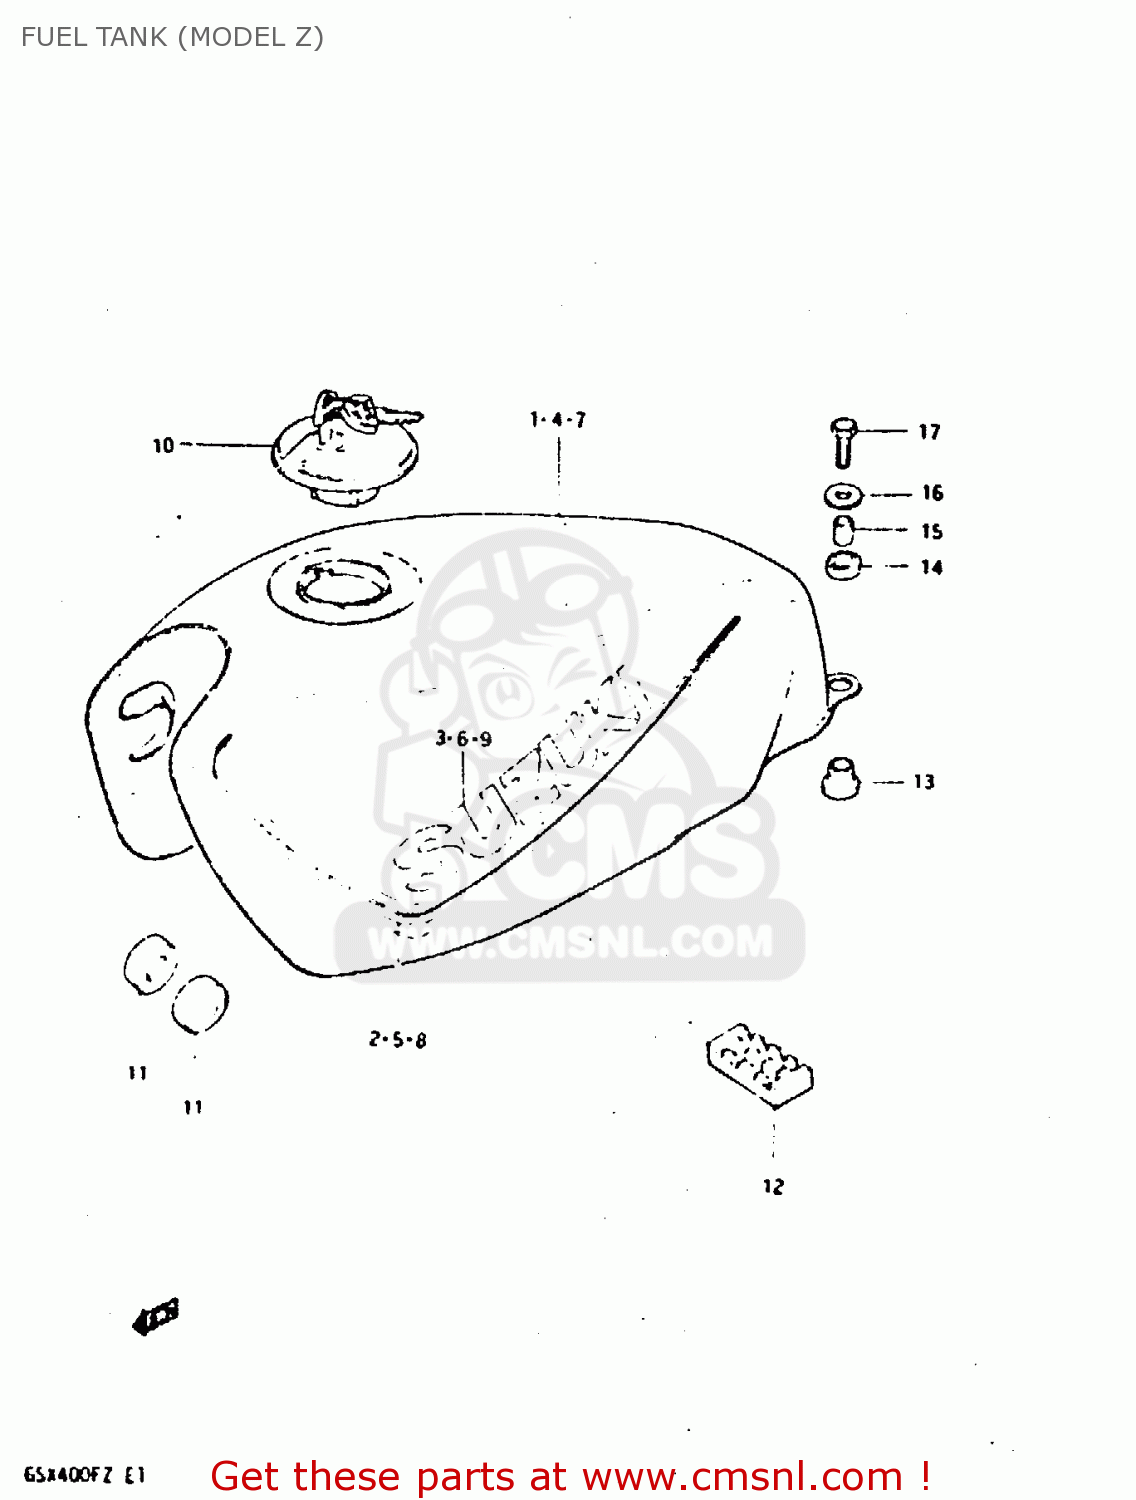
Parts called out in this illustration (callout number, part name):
1	TANK, FUEL (BLUE)
2	TAPE SET
3	EMBLEM(WHITE)
4	TANK, FUEL (SILVER)
5	TAPE SET
6	EMBLEM(ORANGE)
7	TANK, FUEL (RED)
8	TAPE SET
9	EMBLEM(WHITE)
10	CAP SET,FUEL TANK
11	CUSHION
12	CUSHION,FUEL TANK CTR
13	CUSHION
14	CUSHION
15	SPACER
16	WASHER (6.5X24X1.6)
17	BOLT
